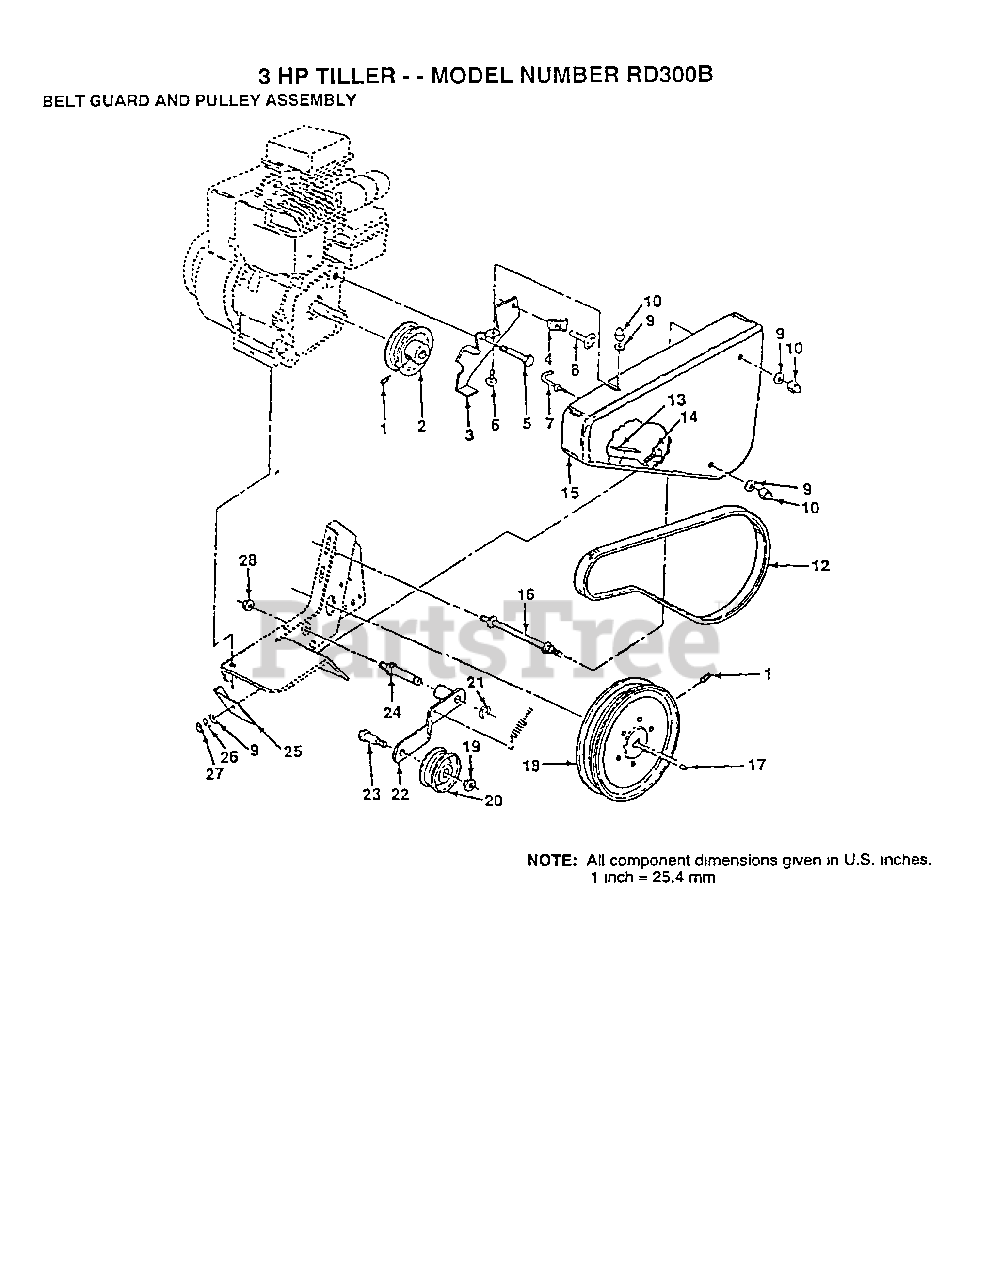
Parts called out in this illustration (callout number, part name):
1	SET SCREW
4	CONDIUT CLIP T
6	BOLT
9	WASHER
10	NUT-CAP TI
13	PAD IDLER TI
14	BOLT T
15	"BELT,GRD"
16	BOLT TI
17	KEY T
18	TRANS SHEAVE RT
19	NUT
21	KLIP RING TI
22	IDLER ARM TI
24	SHAFT IDLER TI
25	SHIELD-DIRT TI
26	LOCKWASHER
28	JAM NUT TI
